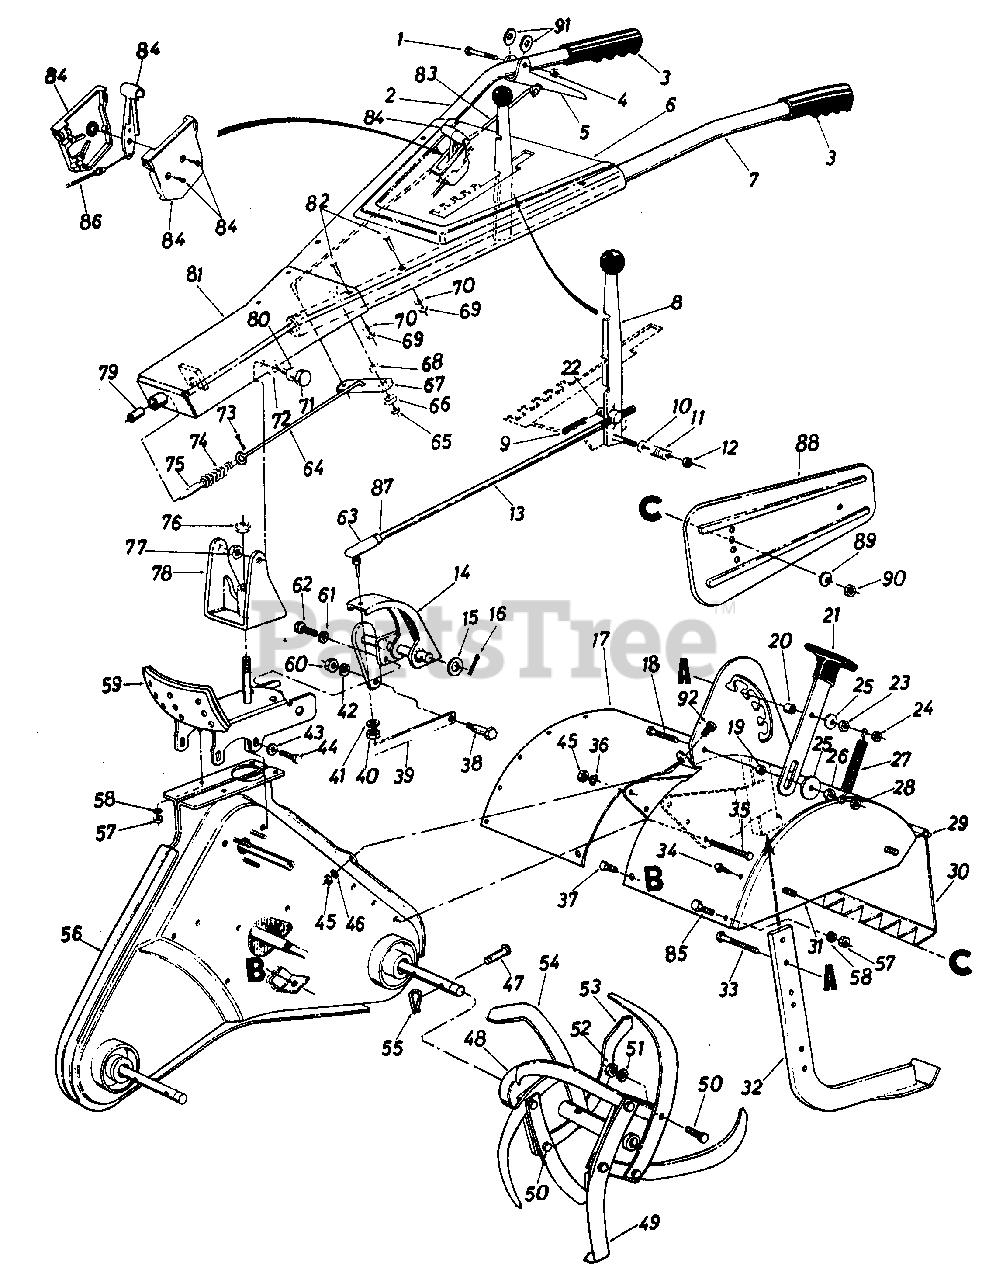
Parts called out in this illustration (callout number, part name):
1	Hex Bolt 1/4-20 x 1.75" Lg.*
2	Handle R.H.
4	Hex Cent. L-Nut 1/4-20 Thd.
5	Clutch Grip
6	Handle Panel Ass'y.
7	Handle L.H.
8	Clutch Handle Ass'y.
9	Hairpin Cotter
10	Belleville Wash. .38" I.D.
11	Compression Spring .88" O . D. x .81 " Lg. .
12	Hex Cent. L-Nut 3/8-24 Thd.
13	Gear Shift Rod
14	Pivot Horn Ass'y.
15	Fl-Wash. .630 I.D. x 1.0" O.D. x .063
16	Cotter Pin 1/8" Dia. x .75" Lg.*
17	Tine Shield Ass'y.
18	Hex Bolt 3/8-16 x 1.5" Lg.*
19	Spacer .38 I.D. x .50 O.D. x .18 Lg.
20	Spacer .38 I.D. x .50 O.D. x .38 Lg.
21	Depth Bar Handle Ass'y w/ Knob
22	Ferrule
23	Hex Nut 3/8-16 Thd.*
24	Hex Ins. L-Nut 3/8-16 Thd.
25	Fl-Wash. .38 I.D. x 1.50 O.D. x . 1 3
26	Hex N ut 3/8-16 Thd.*
27	Spring Depth Bar
28	Hex Ins. L-Nut 3/8-16 Thd.
29	Hinge Rod
30	Tine Shield Hinge Flap Ass'y.
31	Side Cover Tine Shield L.H.
31	Side Cover Tine Shield R.H.
32	Depth/Drag Bar Ass'y.
33	Hex Bolt 3/8-16 x 1.75" Lg.*
34	Hex Wash. Hd. Self-Tap Scr. 5/16-18 x .62" Lg.
34	Speed Nut
35	Hex Bolt 3/8-24 x 3.0" Lg.
36	L-Wash. 3/8" I.D.*
37	Hex Wash. Hd. Self-Tap Scr.
38	Shoulder Bolt .50" Dia. x .25" Lg.
39	Control Bracket
40	Hex Ins. L-Nut 3/8-24 Thd.
41	L-Wash. 3/8" I.D.*
42	L-Wash. 3/8" I.D.*
43	Belleville Wash.
44	Hex Wash. Hd. Self-Tap Scr.
45	Hex Nut 3/8-24 Thd.*
46	L-Wash. 3/8" Scr.*
47	Clevis Pin
48	Tine Adapter Ass'y.
49	L.H. Tine Ass'y. Comp.
49	R.H. Tine Ass'y. Comp.
50	Hex Bolt 3/8-24 x 1.25" Lg.*
51	L-Wash. 3/8" I.D.*
52	Hex Nut 3/8-24 Thd.*
53	Tine R.H.
54	Tine L.H.
55	Hairpin Cotter
56	Chain Case Ass'y. Comp.
57	Hex Nut 5/16-18 Thd.*
58	L-Wash. 5/16" I.D.*
59	Handle Positioner Ass'y.
60	Hex Ins. L-Nut 3/8-16 Thd.
61	L-Wash. 5/16" I.D.*
62	Hex Wash. Hd. Self-Tap Scr.
63	Rod End 3/8-24 Thd.
64	Lower Handle Control Rod
65	Hex Nut 5/16-18 Thd.*
66	Pivot Handle Brg.
67	Pivot Handle Link
68	Bushing Wash.
69	Hex Nut 5/16-18 Thd.*
70	L-Wash. 5/16" I.D.*
71	Shld. Bolt .500" Dia. x .660
72	Belleville Wash. .505" I.D. x 1.00" O.D.
73	Cotter Pin 1/8" Dia. x .75" Lg. .*
74	Compression Spring
75	Locking Pin
76	Hex Ins. L-Nut 5/8-16 Thd.
77	Hex Top L-Nut 3/8-16 Thd.
78	Pivot Brkt. Ass'y.
79	Sleeve Brg. .50" I.D. x .62" O.D. x 1.12" Lg.
80	Fl-Wash. .50" I.D. x 1.00" O.D. x .090
81	Handle Mtg. Brkt. Ass'y.
82	Carriage Bolt 5/16-18 x 1.75" Lg.*
83	Handle Lock Rod
84	Throttle Control Box Ass'y.
85	Hex Bolt 5/16-18 x .75" Lg.*
86	Throttle Control Wire
87	Hex Jam Nut 3/8-24 Thd.
90	Hex Nut 5/16-18 Thd.
91	Fl-Wash. 1/4 " I.D.
92	Hex Bolt 3/8-24 x .75" Lg.
